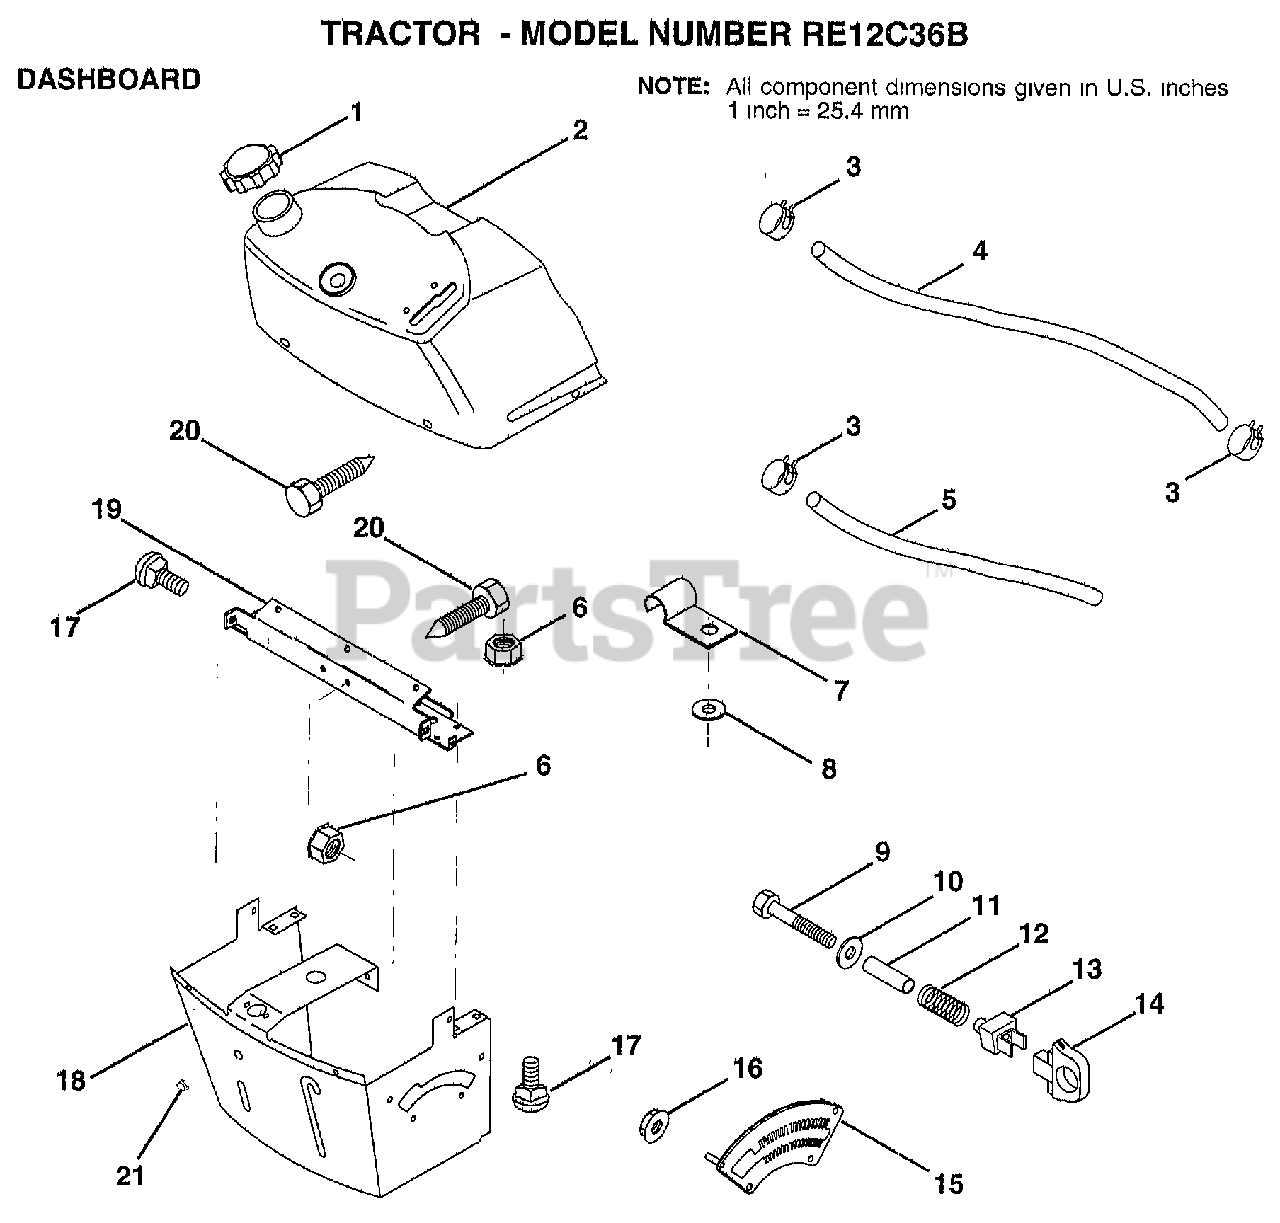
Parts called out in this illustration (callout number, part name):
1	CAP BLK FUEL LR
2	TANK.ASM.DASH.LR
3	HOSE CLAMP
5	FUEL LINE T
6	NUT HXKEP 1/4X20
7	CLIP T
8	WASHER PM
9	BOLT
11	SPACER SPLIT
12	SPRING M
13	"KNOB,HGT RETAINER"
14	KNOB
15	ADJUSTER QUAD
16	NUT
17	BOLT
18	SUPT ASSY DASH
19	CROSS BRACE
20	SCREW.1/4-20X1/2
21	PLUG DOME
